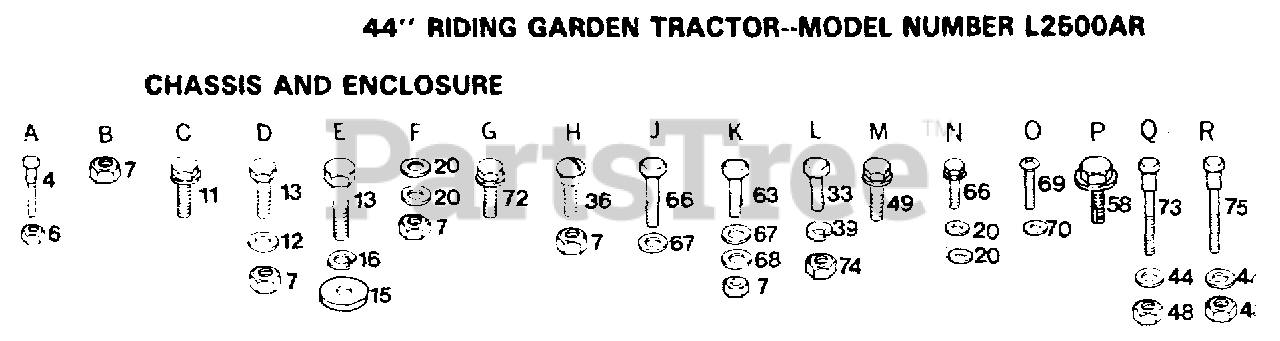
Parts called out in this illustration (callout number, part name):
11	SCREW
12	WASHER
15	WASHER
16	LOCKWASHER
20	WASHER
33	BOLT LT
36	BOLT
39	LOCKWASHER
49	SCREW LT
63	BOLT
66	SCREW GTV
67	WASHER HYT
68	WASHER
69	SCREW
73	BOLT T
75	SHOULDER BOLT ST
